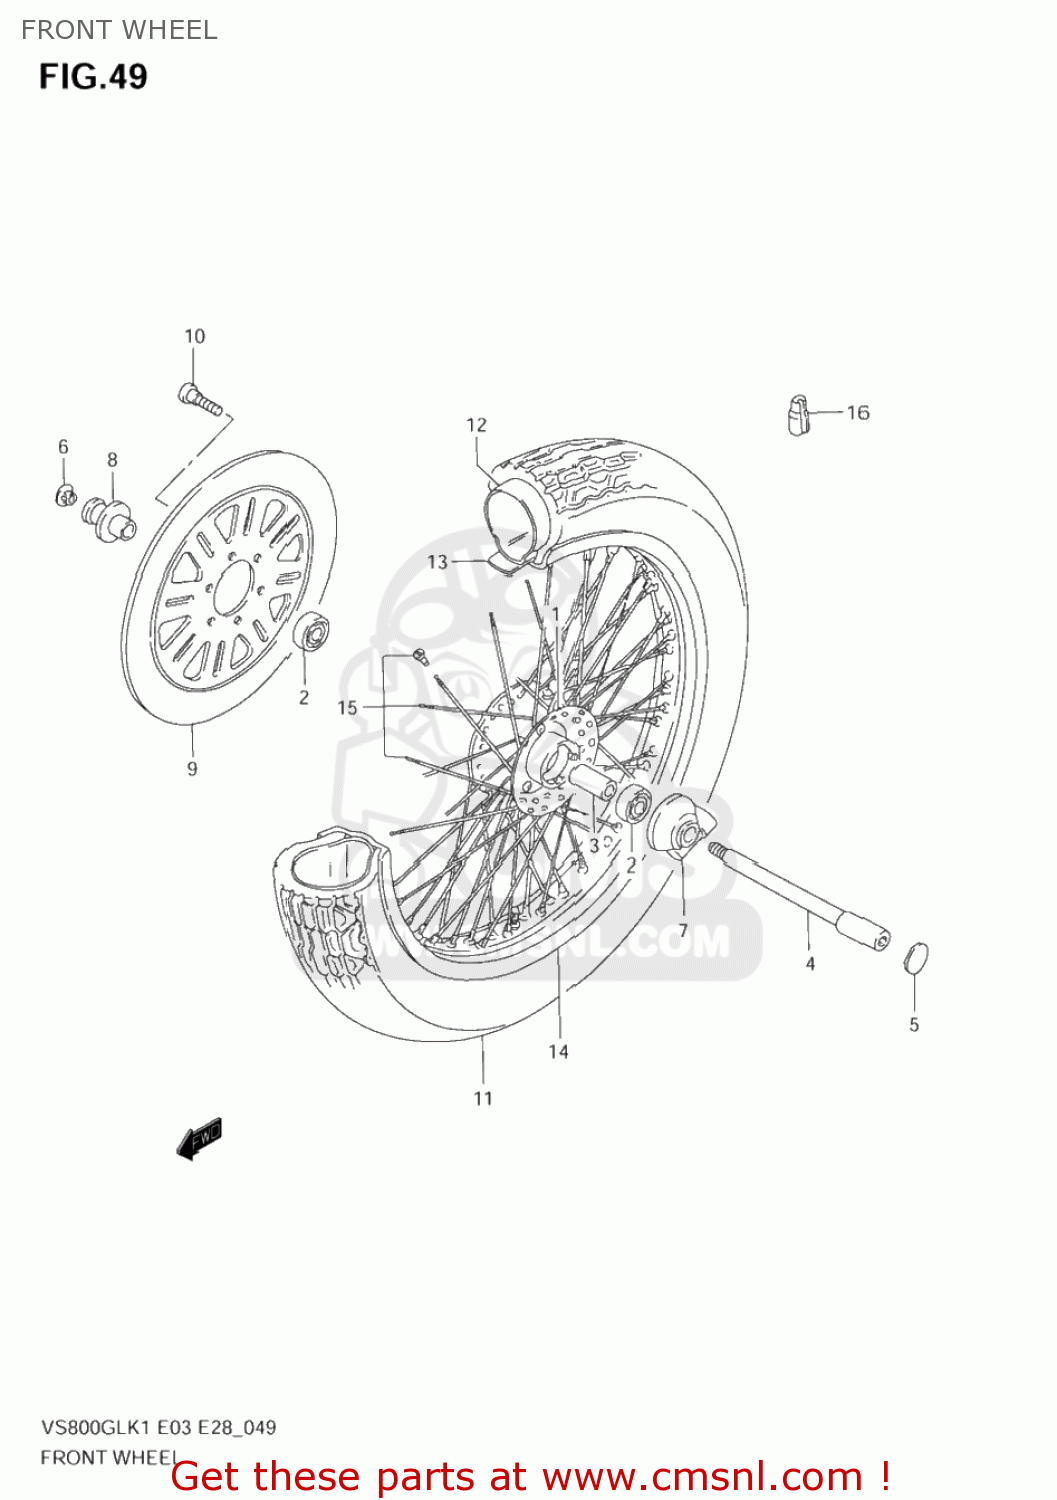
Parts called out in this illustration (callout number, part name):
1	HUB ASSY,FR
2	BEARING
3	SPACER(15.3X21.7X65)
4	AXLE,FR
5	CAP,FR AXLE
6	CAP,FR AXLE
7	BOX ASSY,SPEEDOMETER GEAR
8	SPACER,FR AXLE
9	DISC,FR BRAKE
10	BOLT 8X33
11	TIRE,FR(100/90-19 57H)
12	TUBE
13	PROTECTOR, INNER TUBE
14	RIM,FR WHEEL(19X2.15 AL)
15	SPOKE SET,FR WHEEL
16	BALANCER,WHEEL
